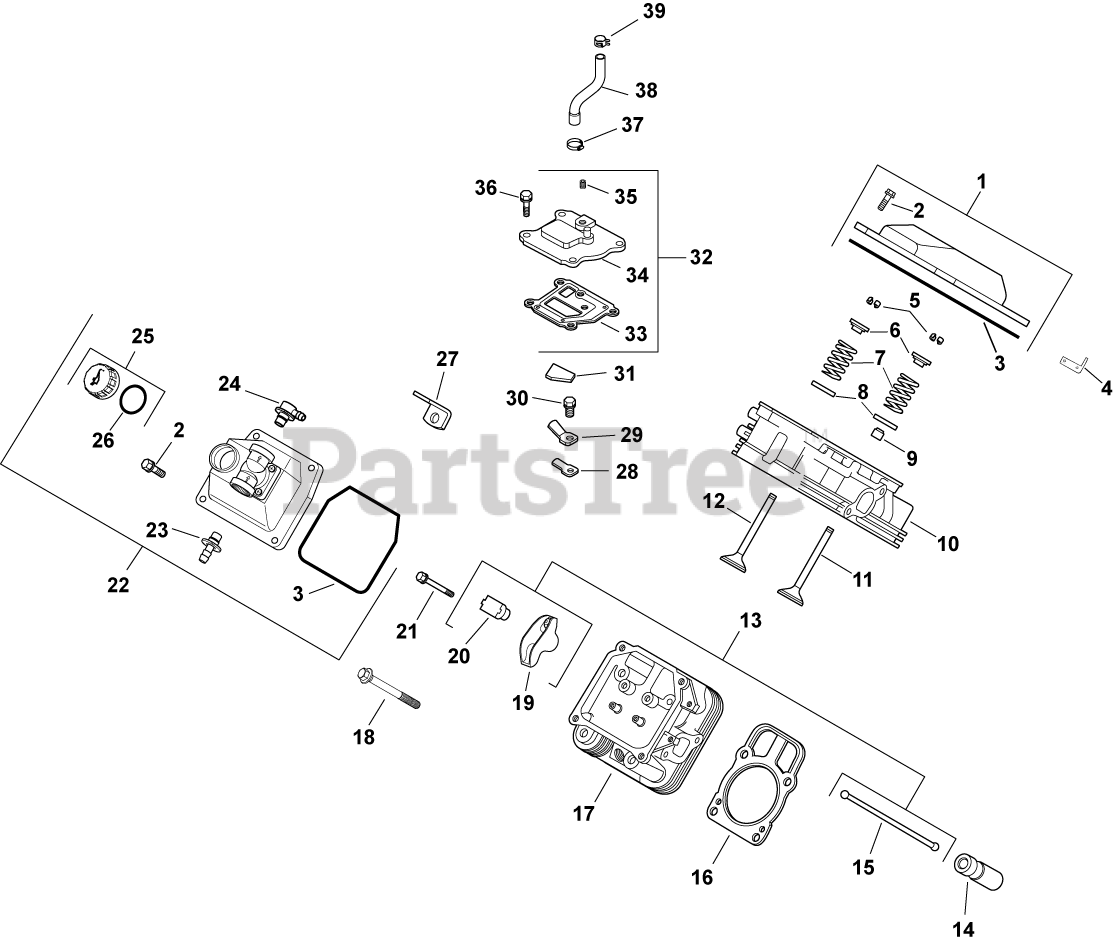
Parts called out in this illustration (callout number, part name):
1	KIT, VALVE COVER-PLAIN
2	SCREW, FLG M6X1.0X30
3	O-RING (YELLOW), VALVE COVER
4	STRAP, LIFTING-USE 25 445 03-S
5	KIT, RETAINER
6	RETAINER, VALVE SPRING - USE 25 173 28-S
7	SPRING, VALVE
8	RETAINER, SPRING
9	SEAL, VALVE STEM - (#2503214S)
10	KIT, #1 CYL HEAD ASSY-(#24318144S)
11	VALVE, INTAKE (STD)
12	VALVE, EXHAUST (STD) - USE 32 016 01-S
13	KIT, VALVE TRAIN
14	LIFTER, HYDRAULIC VALVE-USE 25 351 10-S
15	ROD, PUSH
16	CYL HEAD GASKET KIT-USE 24 841 04-S
17	KIT, #2 CYL HEAD ASSY - (#24318150S)
18	SCREW - USE 62 086 08-S
19	ARM, ROCKER
20	PIVOT, ROCKER ARM
21	SCREW, FLG M6X1.0X34
22	KIT, VALVE COVER-FUEL PUMP
23	KIT, STRAIGHT FITTING
24	KIT, 90 DEG. FITTING
25	CAP ASSY, OIL FILL (YELLOW)
26	O-RING-USE 24 153 32-S
27	STRAP, LIFTING
28	REED, BREATHER
29	RETAINER, REED
30	SCREW, FLG THD FRM M5X.8X10
31	FILTER, BREATHER
32	KIT, BREATHER ASSEMBLY
33	GASKET, BREATHER-USE 24 041 67-S
34	COVER, BREATHER -USE 24 033 01-S
35	PLUG, CTSK PIPE 1/8"
36	SCREW,FLG THD FRM M6X1.0X20-(#25086396S)
37	CLAMP, HOSE (KM)-USE 25 237 31-S
38	HOSE, BREATHER
39	CLAMP, BAND SPRING HOSE-(#2523737S)
2401602-S	VALVE, EXHAUST (.25)
2401702-S	VALVE, INTAKE (.25)
